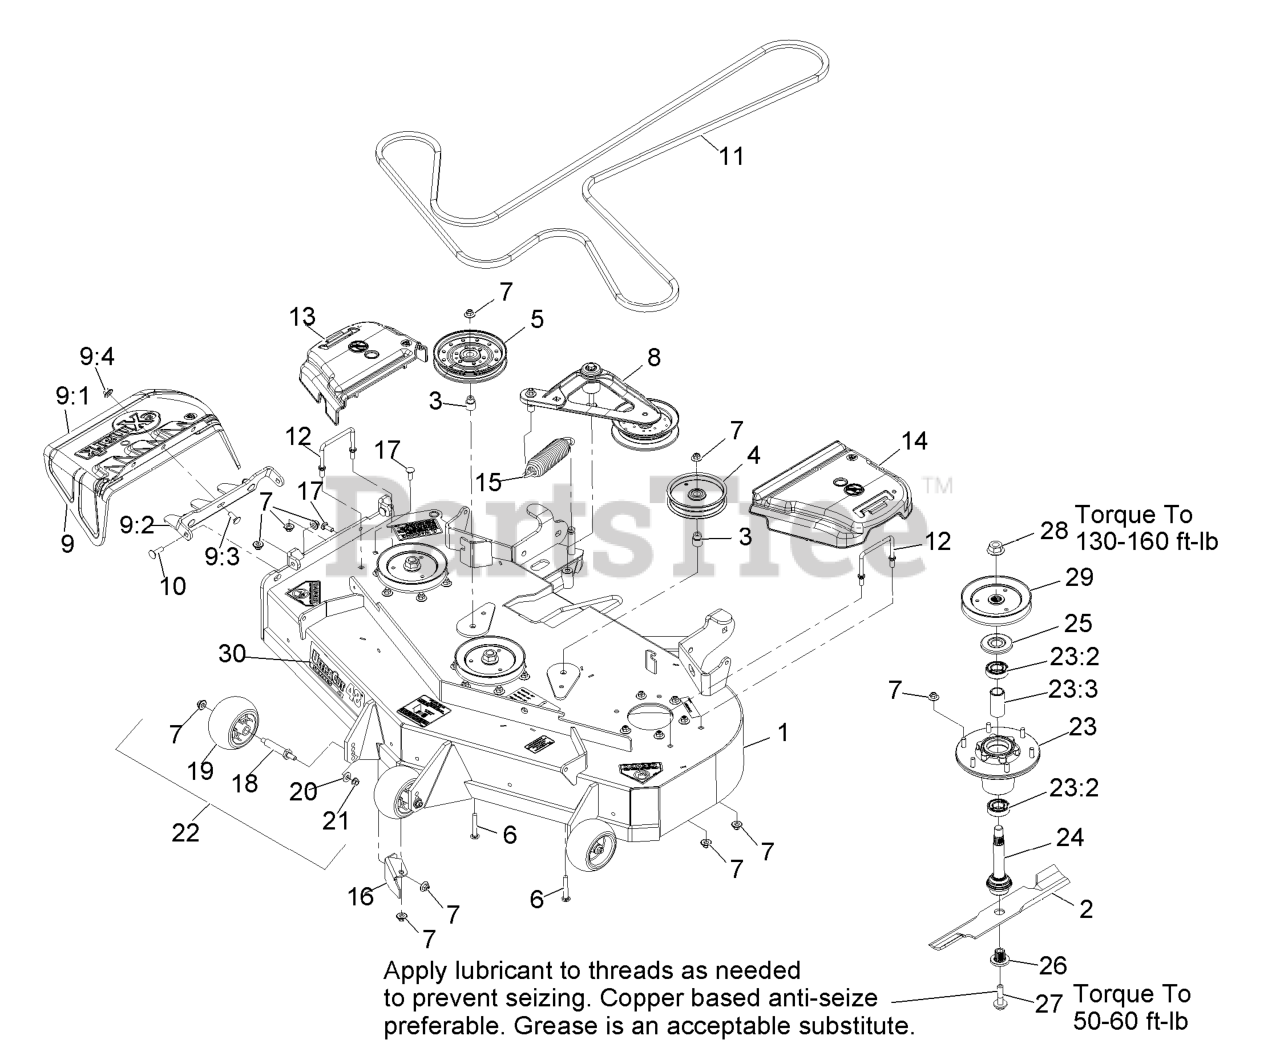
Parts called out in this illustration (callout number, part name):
1	ASM,DECK W/DECALS 48
3	BUSHING-IDLER
4	PULLEY-IDLER
6	SCREW-CARR
7	Nut-Nyloc 3/8-16 Flg
8	DECK IDLER ASM
9	ASM,DISCHARGE CHUTE
9:1	CHUTE,DISCHARGE
9:2	BRACKET,DISCHARGE CHUTE
9:3	SCREW-CARR
9:4	Nut-Nyloc 3/8-16 Flg
10	Bolt-Carriage 3/8-16 X 1 1/4
11	BELT
12	WIREFORM-COVER
13	COVER-BELT, RH
14	COVER-BELT, LH
16	BAFFLE,DISCHARGE
17	SCREW-CARR
19	ROLLER-SCALP, ANTI
20	WASHER-BELLEVILLE
21	NUT-HHF, WHIZ
23	ASM-CUTTER HSG WITH BEARINGS
23:2	BEARING-BALL
23:3	SPACER-BEARING
24	ASM-SPINDLE AND SEAL
25	GUARD,BEARING TOP .989
26	BUSHING,SPLINED
27	SCREW,SEMS 1/2-20 X 2.19
28	NUT-FLANGE
29	SHEAVE,BLADE DRIVE 5.90
30	DECAL,ULTRACUT 48 SERIES
